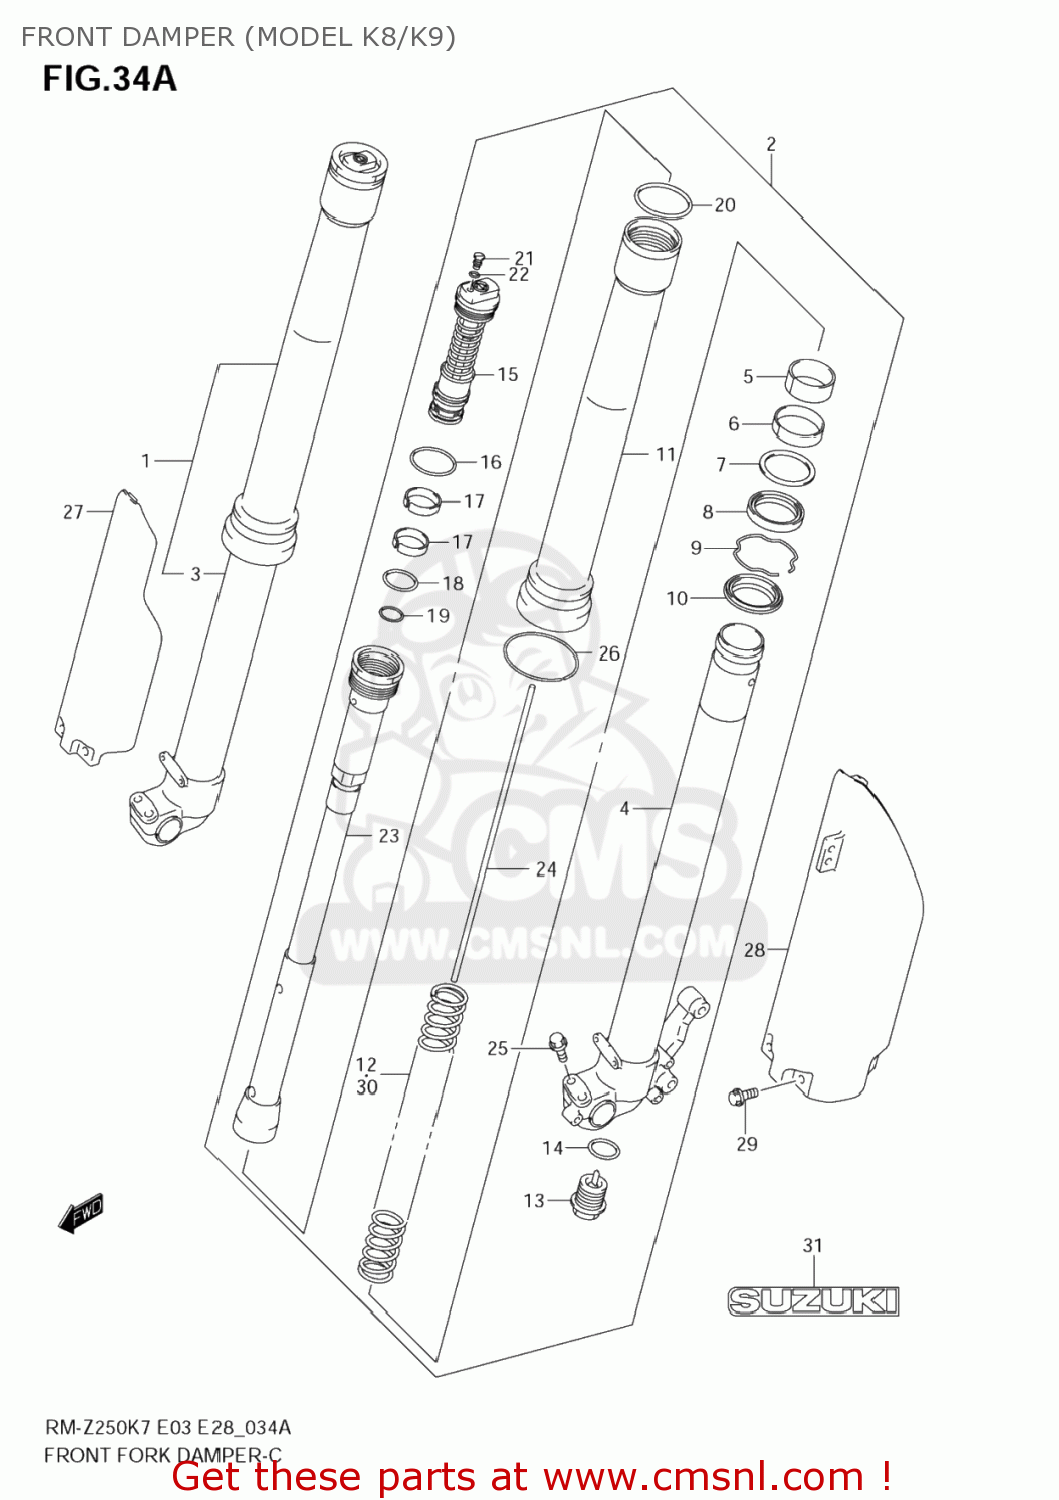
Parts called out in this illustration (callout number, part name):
1	DAMPER ASSY,FR FORK,R
2	DAMPER ASSY,FR FORK,L
3	TUBE,INNER,R
4	TUBE,INNER,L
5	BUSH,SLIDE
6	BUSH,GUIDE
7	SPACER,SEAL
8	SEAL,OIL
9	RING,OIL SEAL STOPPER
10	SEAL,DUST
11	TUBE,OUTER
12	SPRING,FR(K=0.44)
13	BOLT,CTR
14	O RING
15	BOLT
16	O RING
17	BUSH,FORK BOLT SLIDE
18	O RING
19	O RING
20	O RING
21	BOLT,PLUG
22	O RING,PLUG
23	DAMPER
24	ROD,PUSH
25	BOLT
26	STOPPER,RING
27	PROTECTOR,FR FORK,R
28	PROTECTOR,FR FORK,L
29	BOLT(6X10)
30	SPRING,FR(K=0.46)
31	EMBLEM,SUZUKI
